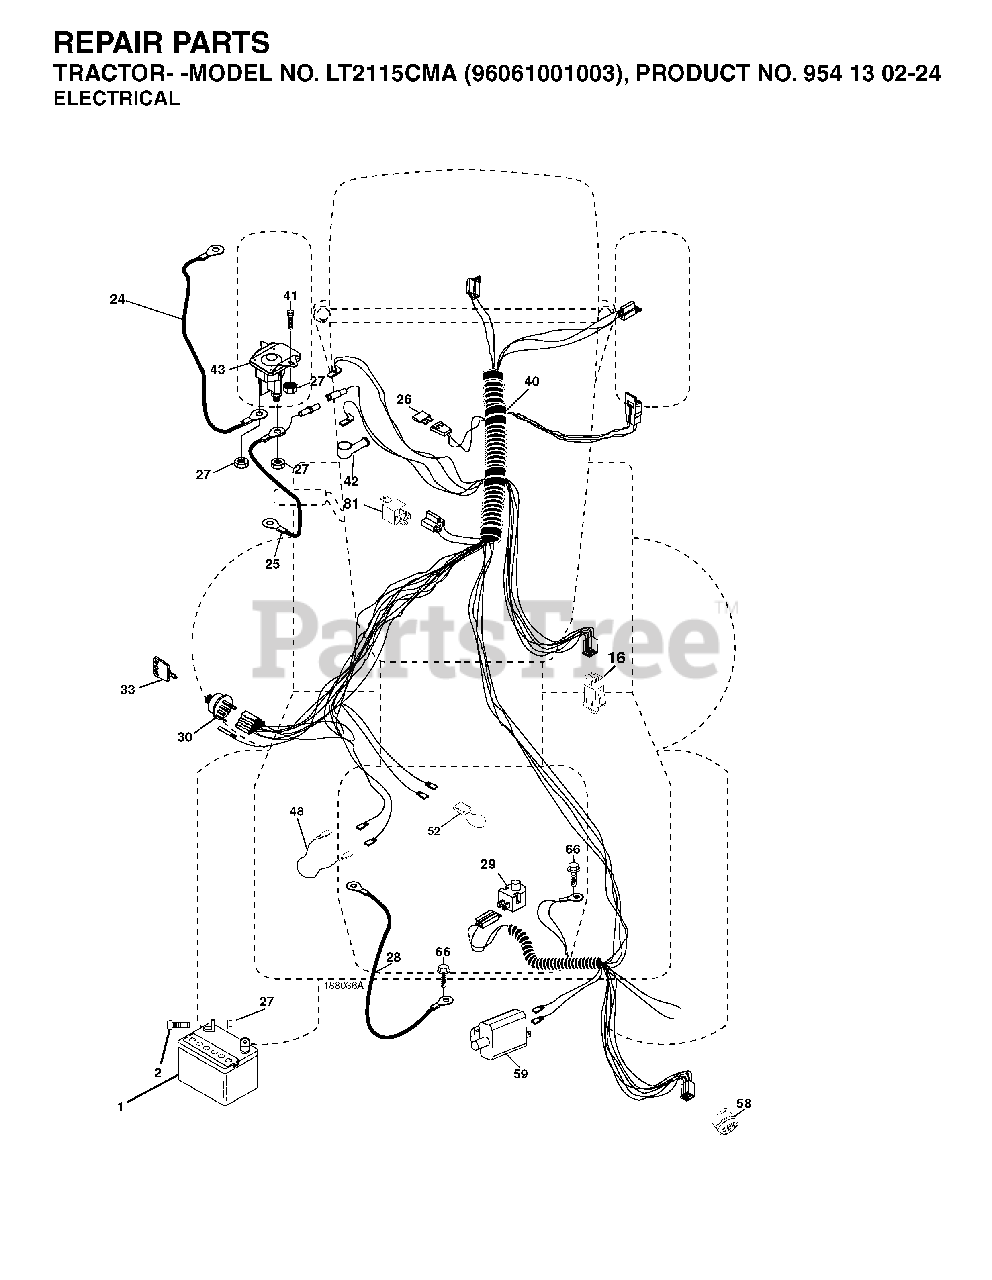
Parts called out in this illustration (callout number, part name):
1	BATTERY 12V .35 AMP
16	SWITCH INTERLOOK PUSH-IN
21	HARNESS ASSY LIGHT
22	LIGHTBULB
24	BATTERY CABLE GT
25	CABLE BATTERY
26	FUSE 20AMP
27	NUT
28	CABLE GROUND
29	SWITCH SEAT
30	IGNITION SWITCH
33	KEY MLD GEN DELTA
42	TERMINAL COVER
43	SOLENOID.W/BRASS.PLUNG
52	WIRE PROTECTION LOOP
58	BUZZER
81	RELAY.ASSY.T
